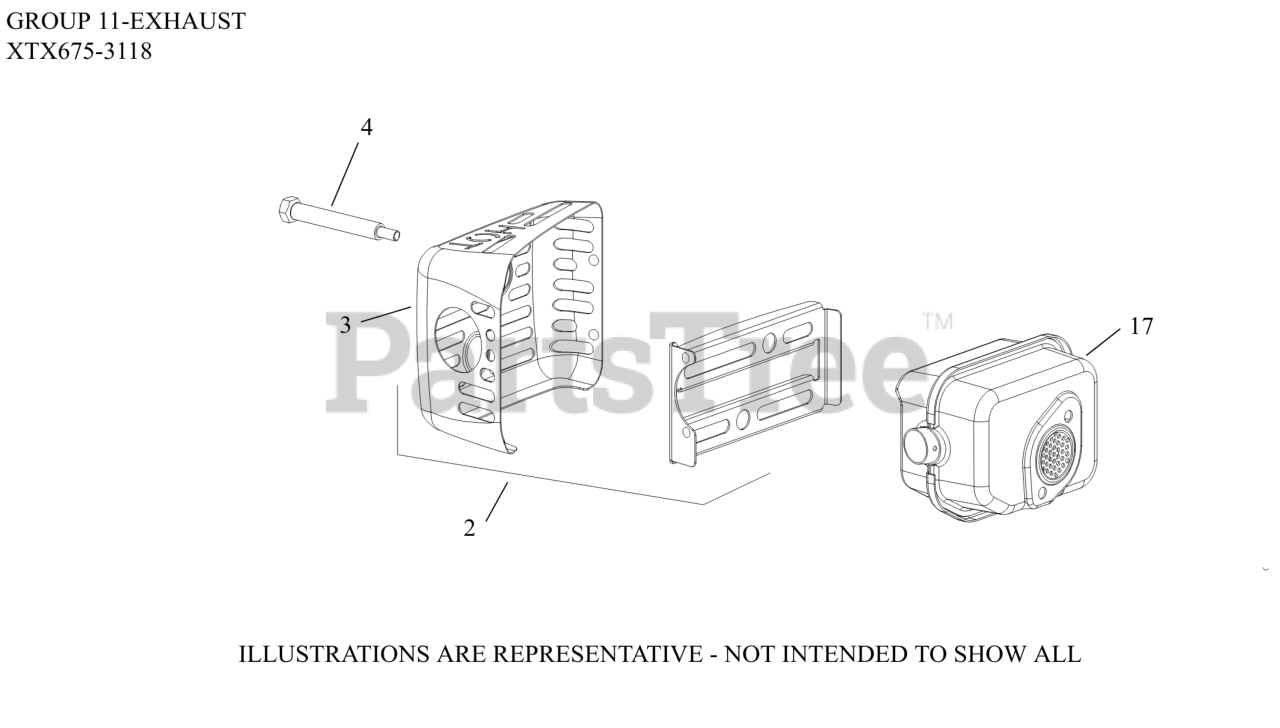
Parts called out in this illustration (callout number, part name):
2	GUARD, MUFFLER ASSEMBLY
3	GUARD, MUFFLER - DISCONTINUED
4	SCREW, SHOULDER
17	MUFFLER, ASSEMBLY
